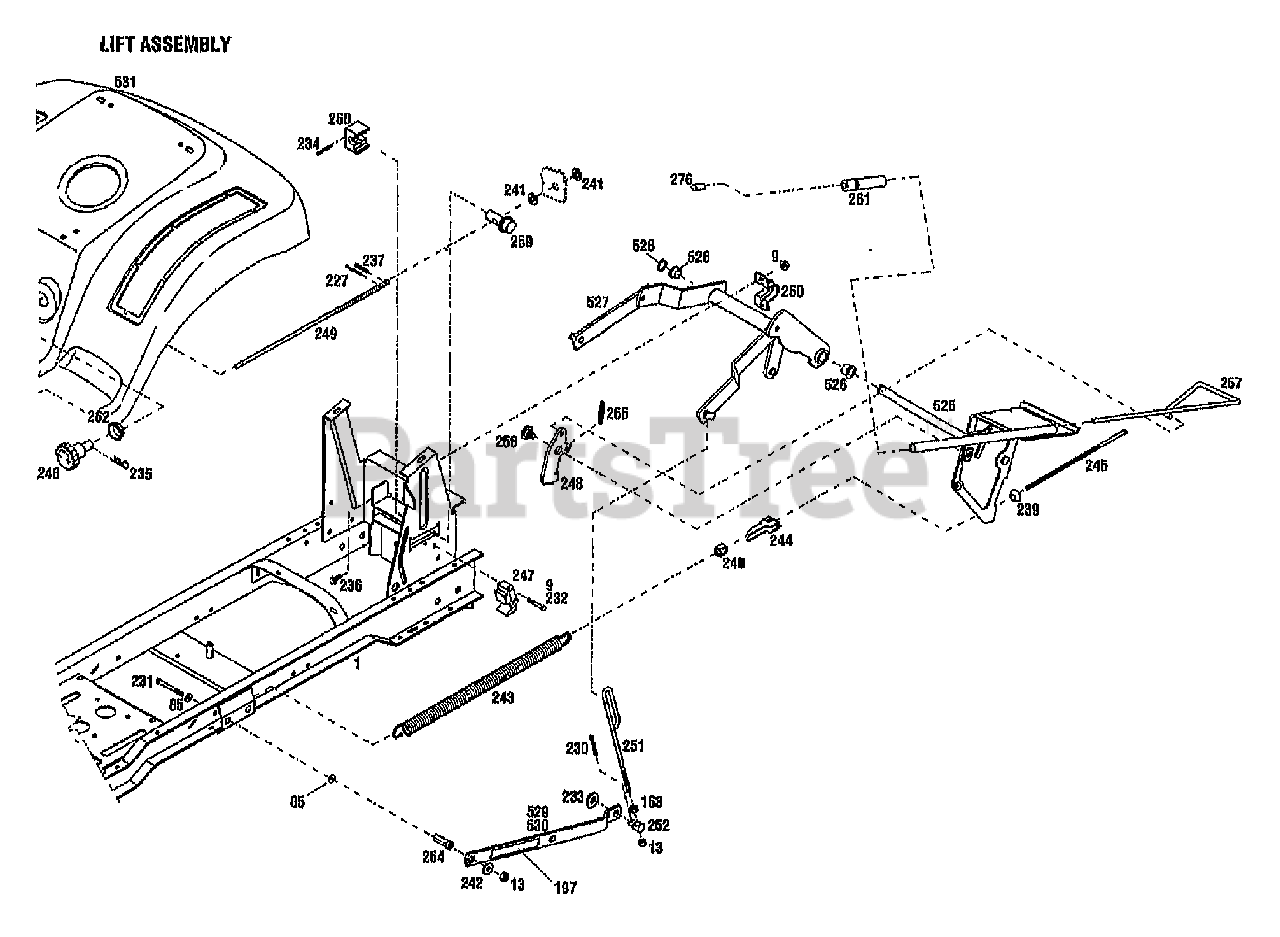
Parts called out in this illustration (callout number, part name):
1	ASSM-FRAME LTX
9	NUT-HFLK 5/16-18 ZP
13	NUT-LOCK 3/8-16
85	WASHER-FLAT 3/8 SAE
163	NUT-HEX 3/8-16 ZP
197	DECAL-WARNING
227	PIN-COTTER .125 X .75 ZP
230	PIN-COTTER .120X1.25 ZP
231	SCR-HH 3/8-16X3.0 G5 ZP
232	SCR-HH 5/16-18X1.5 G5 ZP
233	WASHER-1.305X.649X.098 ZP
234	PIN-DRIVE
235	PIN-HITCH
236	SCR-HFLK 5/16-18X.75 ZP
237	PIN-ROLL .156X1.0
239	BEARING-SPHERICAL
240	NUT-SPECIAL 5/16-18
242	WASHER-1.5X.375X.18 ZP
243	SPRING-LIFT ASSIST
244	AXLE-FRONT
245	SCR-LIFT ASSIST
246	KNOB-HEIGHT ADJUST
247	BLOCK-DETENT
249	KIT-SVC SCR HGT ADJ
250	CLAMP-LIFT
252	SWIVEL-LIFT REAR
254	SPACER
255	SPRING-EXTENSION
256	SCR-SHOULDER
259	BLOCK-HEIGHT ADJUST
260	COLLAR-HEIGHT ADJUST
261	GRIP-LIFT
262	GROMMET-SNAP BUSHING
276	BUTTON-LIFT
525	HANDLE-LIFT
528	RING-RETAINING EXT .694 ID
529	LINK-LIFT W/DECAL
530	LINK-LIFT W/DECAL
531	FENDER-RED W/DECALS
600	PAINT-BLACK SPRAY
601	PAINT-RED SPRAYCAN POWDER
